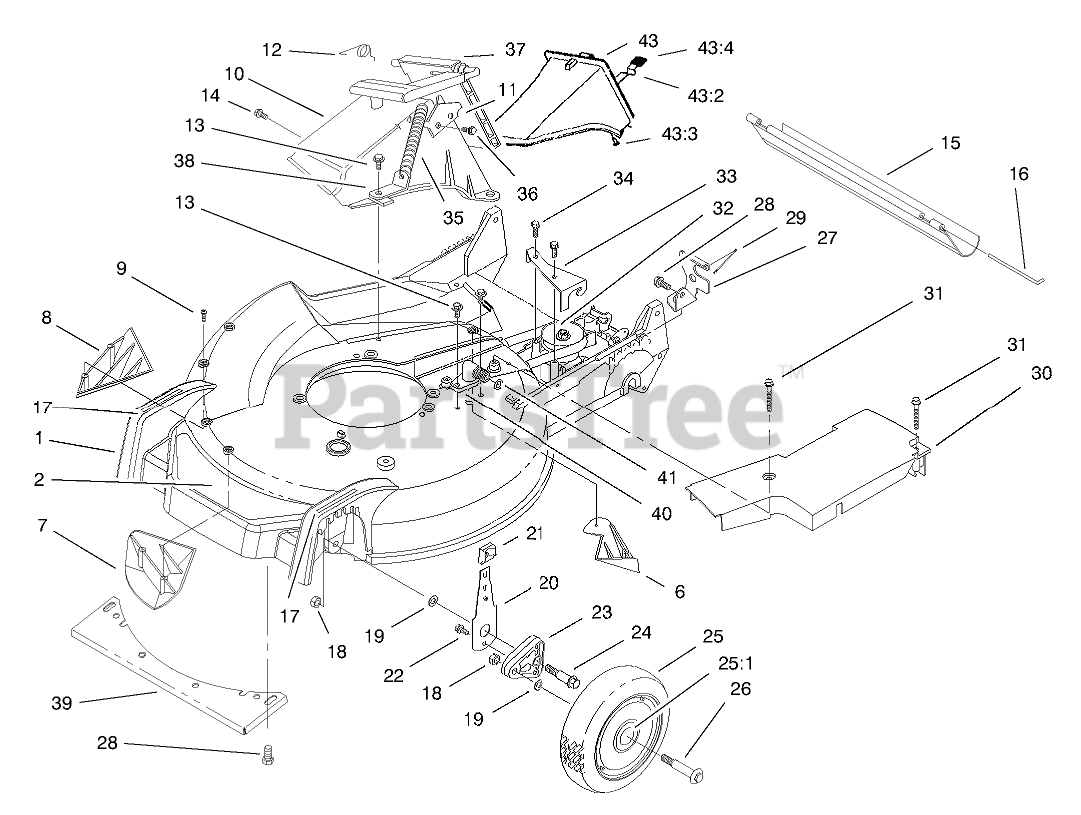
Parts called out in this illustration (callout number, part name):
1	HOUSING ASM
2	DECAL - DECK
6	KICKER-REAR
7	KICKER-FRONT
8	KICKER-RH
9	SCREW-PPH
10	TUNNEL-DISCHARGE
11	LATCH-PLATE
12	RETAINER-DOOR
13	SCREW-HWH
14	SCREW AND WASHER ASM
15	SHIELD-TRAILING
16	ROD-SHIELD
18	NUT-LOCK
19	WASHER
20	FRONT SPRING ARM ASM
21	KNOB-ARM
22	SCREW-HWH
23	ARM-PIVOT, FRONT
24	BOLT-SHOULDER
25	WHEEL AND TIRE ASM
25:1	WHL & TIRE ASSEMBLY
26	BOLT-WHEEL
27	Bracket-Adj. Trac
28	SCREW-HWHTF
29	RETAINER-CABLE
30	COVER-BELT
31	SCREW-HHFTF
32	GEARCASE ASM
33	Bracket-Guide
34	SCREW-HWHTF
35	SPRING-DOOR
36	SCREW-PLASTITE
37	DISCHARGE DOOR ASM
38	BRACKET-SPRING
39	Shield-front
40	FITTING-WASHOUT
41	O-RING
43	DISCHARGE PLUG ASM
43:2	LATCH-PLUG, DISCHARGE
43:3	RIVET-HEAD, FLAT
43:4	GRIP-LATCH
